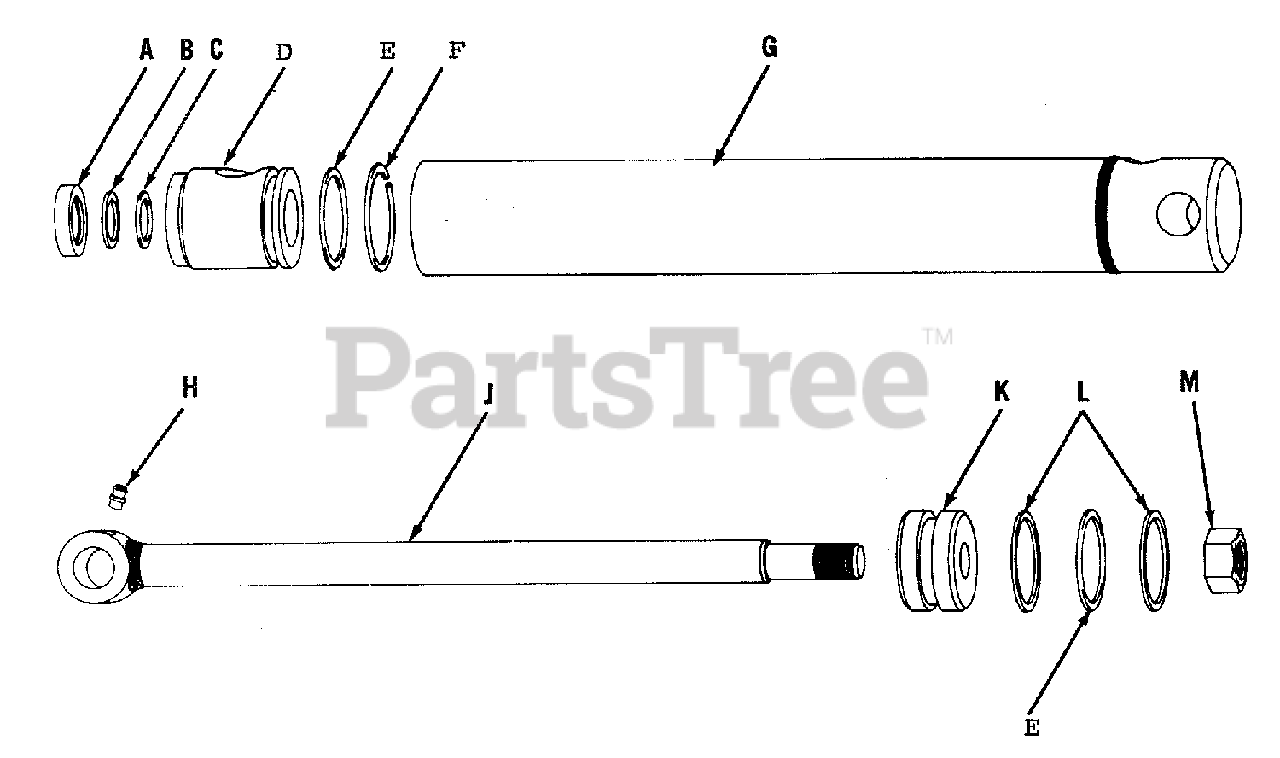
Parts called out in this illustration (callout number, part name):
A	WIPER, Ring
B	WASHER, Back-up
C	RING, "O"
D	HEAD, Cylinder
E	RING, "O"
F	RING, Retaining
G	TUBE ASSEMBLY, Cylinder
H	FITTING, Grease
J	ROD ASSEMBLY, Piston
L	WASHER, Back-up
M	NUT, Hex, Full Lock, 5/8"-18 NF
N	MAJOR SEAL REPAIR KIT
